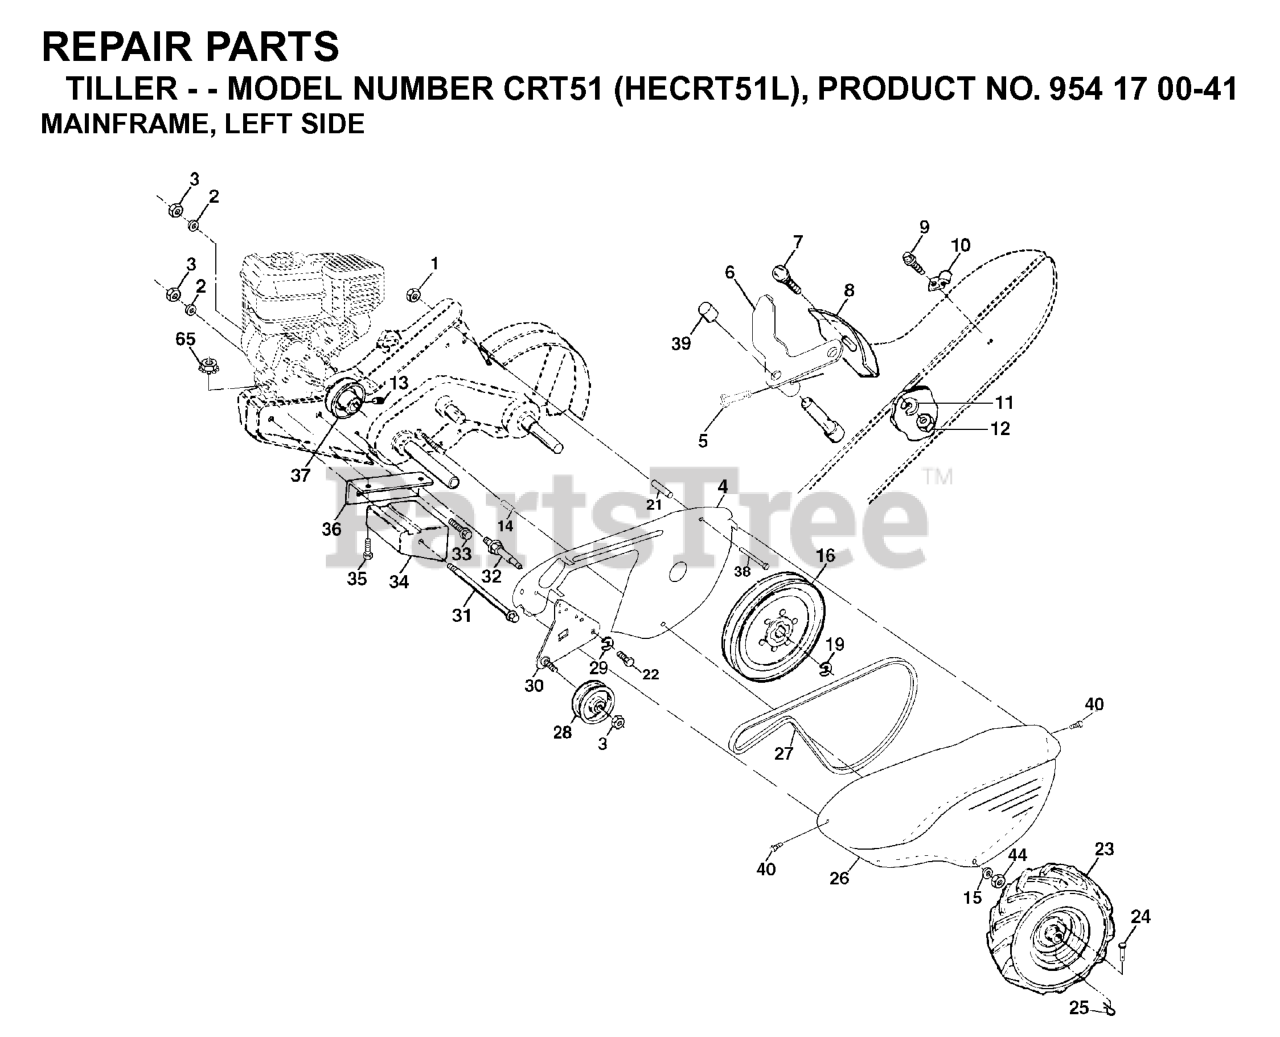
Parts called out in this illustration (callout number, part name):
1	NUT
2	WASHER, LOCK 3/8
3	NUT.HEX.3/8-16UNC
4	SHIELD
5	PIN.SPIROL.FLARED
6	LEVER ASM CRT
8	PANEL.INDICATOR.SHIFT.BLACK
9	TAPPING SCREW
10	CONDUIT.CLIP.PLATED
11	LOCKWASHER
12	NUT
14	SPACER-SPLIT.327 X .42
15	WASHER
16	SHEAVE, TRANSMISSION
19	RETAINING RING LT
21	SPACER CRT
23	TIRE.16X4-8.CHEVRON.TILLER
24	RIVET,DRILLED
25	RETAINER M
26	RP BELT GUARD
27	V-BELT
28	PULLEY-IDLER TI
30	BRACKET.ASM.IDLER.BLACK
31	BOLT.FIN.HEX.3/8-16UNC
32	SHIFT ARM CRT
33	BOLT
34	COUNTERWEIGHT.LH.CRT
35	Bolt Fin Hex 5/16 - 18 Unc x 2 Gr. 2
36	BRACKET LH CRT
37	RP.ENGINE PULLEY
38	BOLT
39	CAP.PLUNGER.BLACK
40	SCREW.HEX.WSH.SLT.#10-24X.50
44	NUT.71038.31-18.HEX.NYLOCK
65	LOCKNUT-FLANGE 5/16-18
